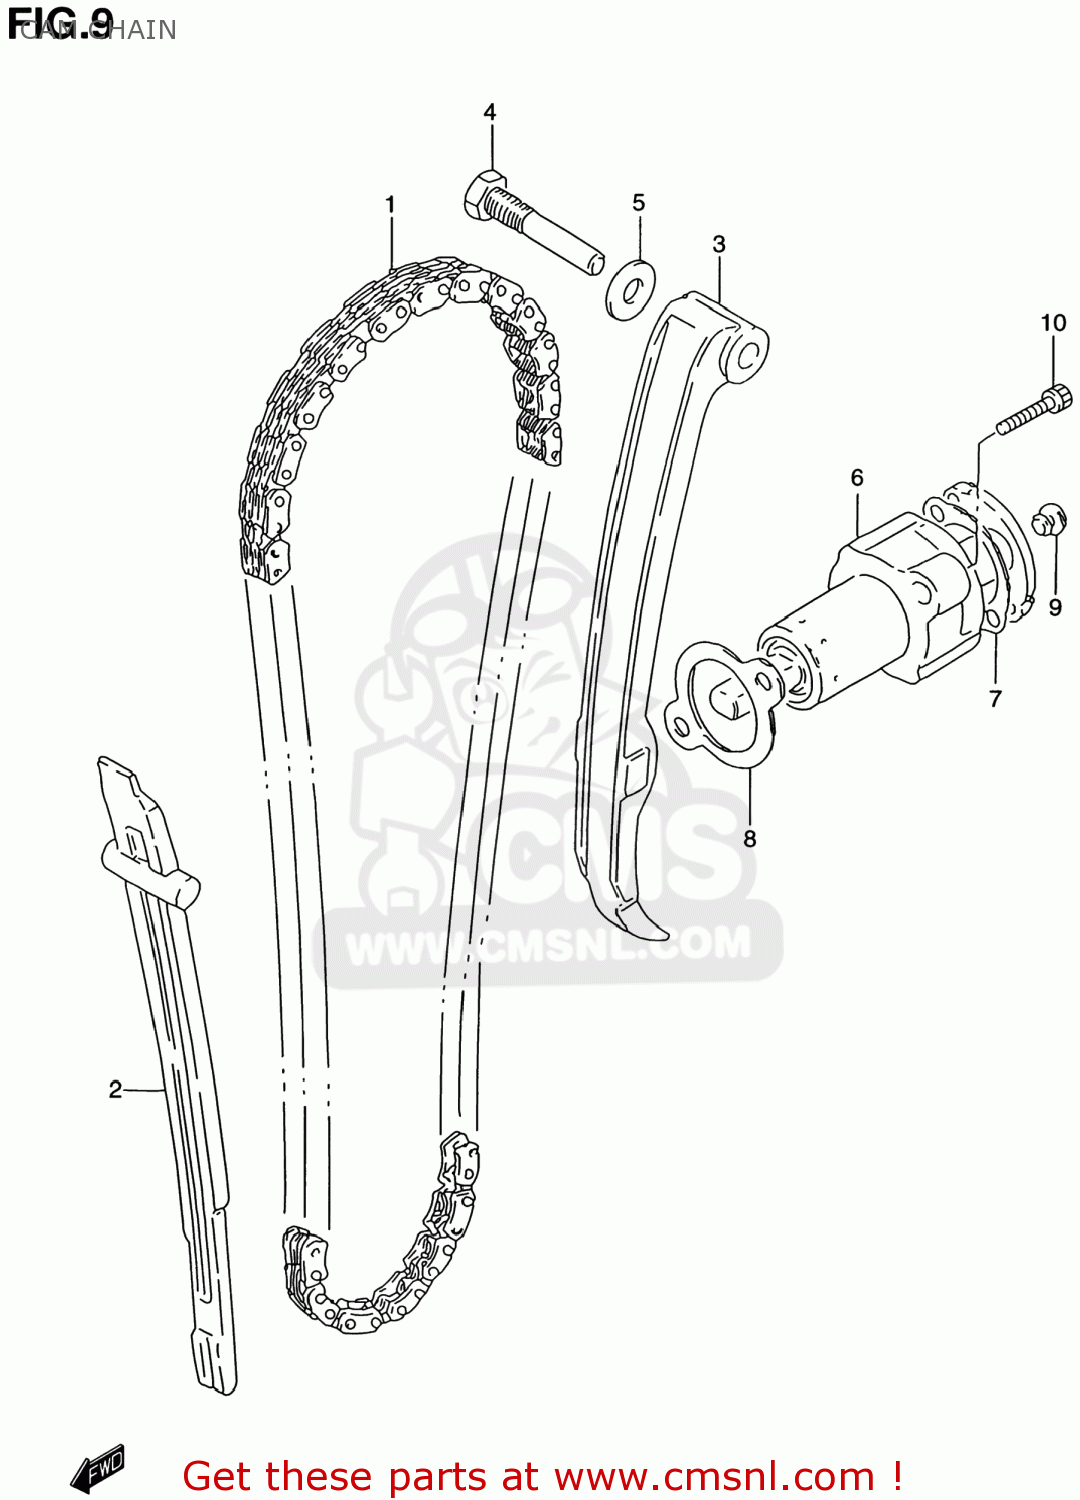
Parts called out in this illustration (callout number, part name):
1	CHAIN,CAMSHAFT DRIVE
2	GUIDE,CAM CHAIN
3	TENSIONER,CAM CHAIN
4	BOLT,CAM CHAIN TENSIONER
5	GASKET 8.2X14X1 (NAS)
6	ADJUSTER ASSY,TENSIONER
7	GASKET,ADJUSTER CAP (NAS)
8	GASKET,TENSIONER ADJUSTER (NAS)
9	PLUG,ADJUSTER
10	BOLT
